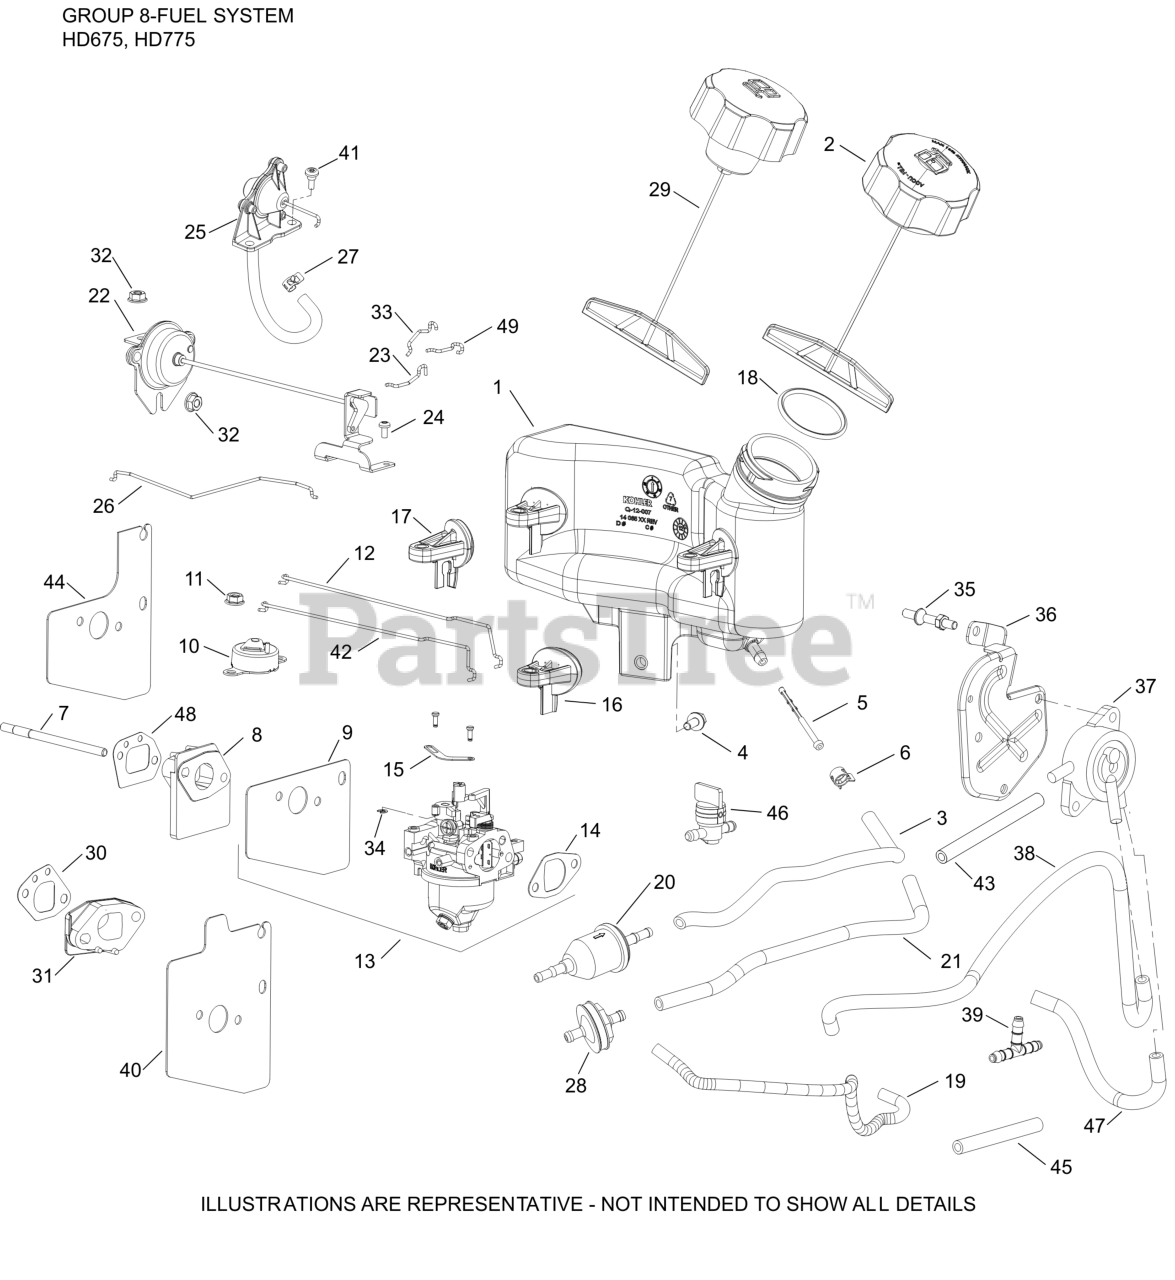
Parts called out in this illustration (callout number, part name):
1	TANK, FUEL
2	FUEL CAP ASSEMBLY
4	SCREW, HEX FLANGE (M6)
6	CLAMP, HOSE (NON-CALIF)(#1423710S)
7	STUD,M6X1.0X100.2MM
8	KIT, SPACER
9	KIT, CARBURETOR HEAT SHIELD GASKET
13	KIT, CARBURETOR 13 MM STD CHOKE
14	KIT, INTAKE GASKET
16	BRACKET, FUEL TANK-DISCONTINUED
17	BRACKET, FUEL TANK-DISCONTINUED
21	HOSE, FUEL LOW-PERMEATION (CKY)
28	FILTER, FUEL
48	GASKET SPACER
NI	KIT,HIGH AL(4000-8000 FT)USE 14 755 04-S
NI	KIT, CARBURETOR REPAIR (RUIXING)
